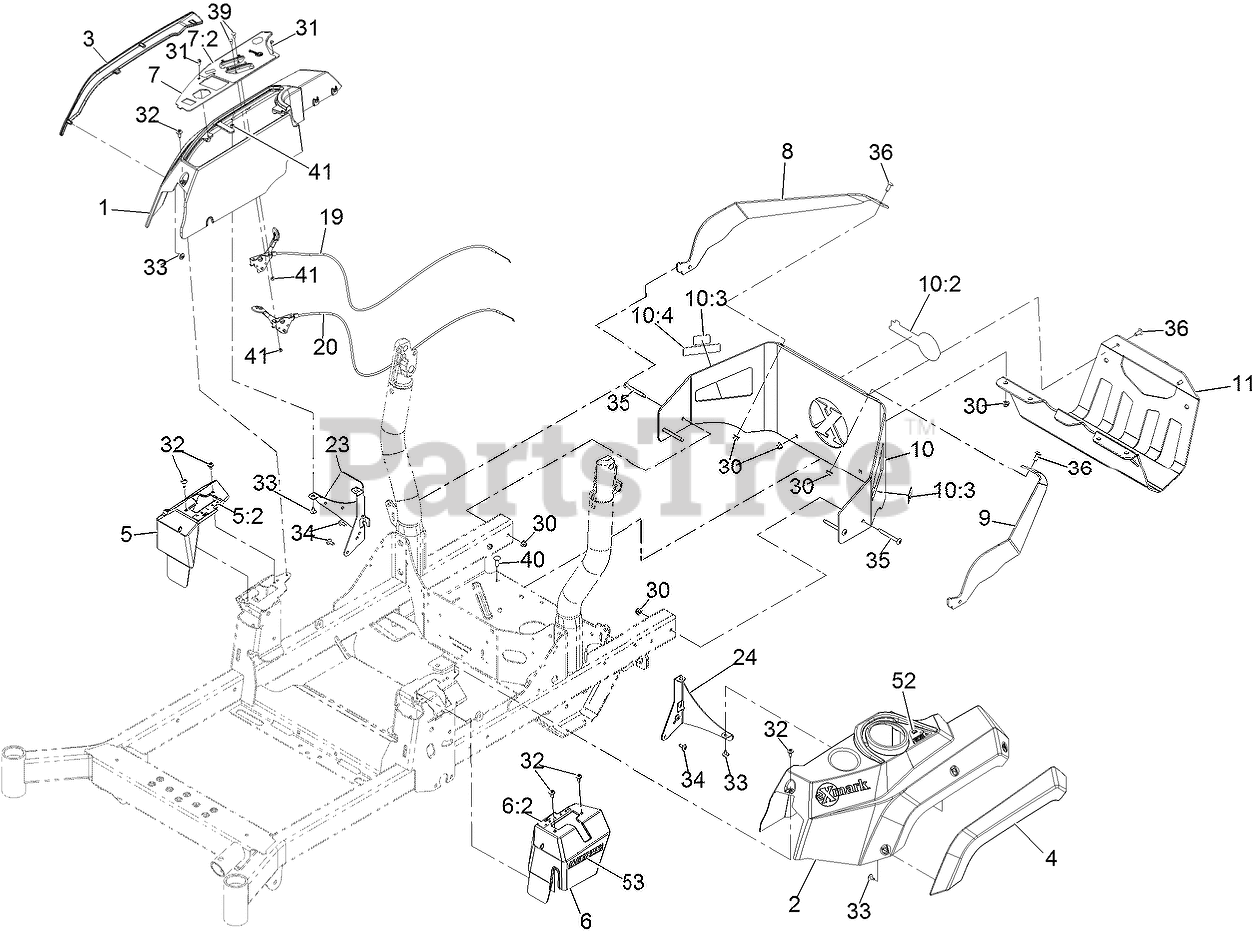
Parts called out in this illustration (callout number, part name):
1	CONSOLE-EXMARK, RH
2	CONSOLE, LH
3	FENDER-RH
4	FENDER-LH
5	COVER-CONTROL, MOTION (RH
5:2	Decal-Control, Motion (RH)
6	COVER-CONTROL, MOTION (LH
6:2	Decal-Control, Motion (LH)
7	ASM-CONTROL PANEL W/EXMARK DECAL
7:2	DECAL-CONTROL PANEL
8	SUPPORT-UPPER, RH
9	SUPPORT-UPPER, LH
10	REAR GUARD ASM
10:2	DECAL, EXMARK LOGO
10:3	DECAL-WARNING
10:4	DECAL-ARRESTOR, SPARK
11	GUARD-MUFFLER
19	CABLE-CONTROL, CHOKE
20	CABLE-CONTROL, THROTTLE
23	SUPPORT-CONSOLE, RH
24	BRACKET-CONSOLE, LH
30	NUT-HF, NI
31	SCREW-HWH
32	SCREW-SHOULDER
33	SCREW-TORX
34	SCREW-TORX
35	SCREW-TORX
36	SCREW-TORX
39	BOLT-CARR
40	SCREW-CARR
41	NUT-LOCK, NI
52	DECAL-FILL, FUEL
53	DECAL-S-SERIES
